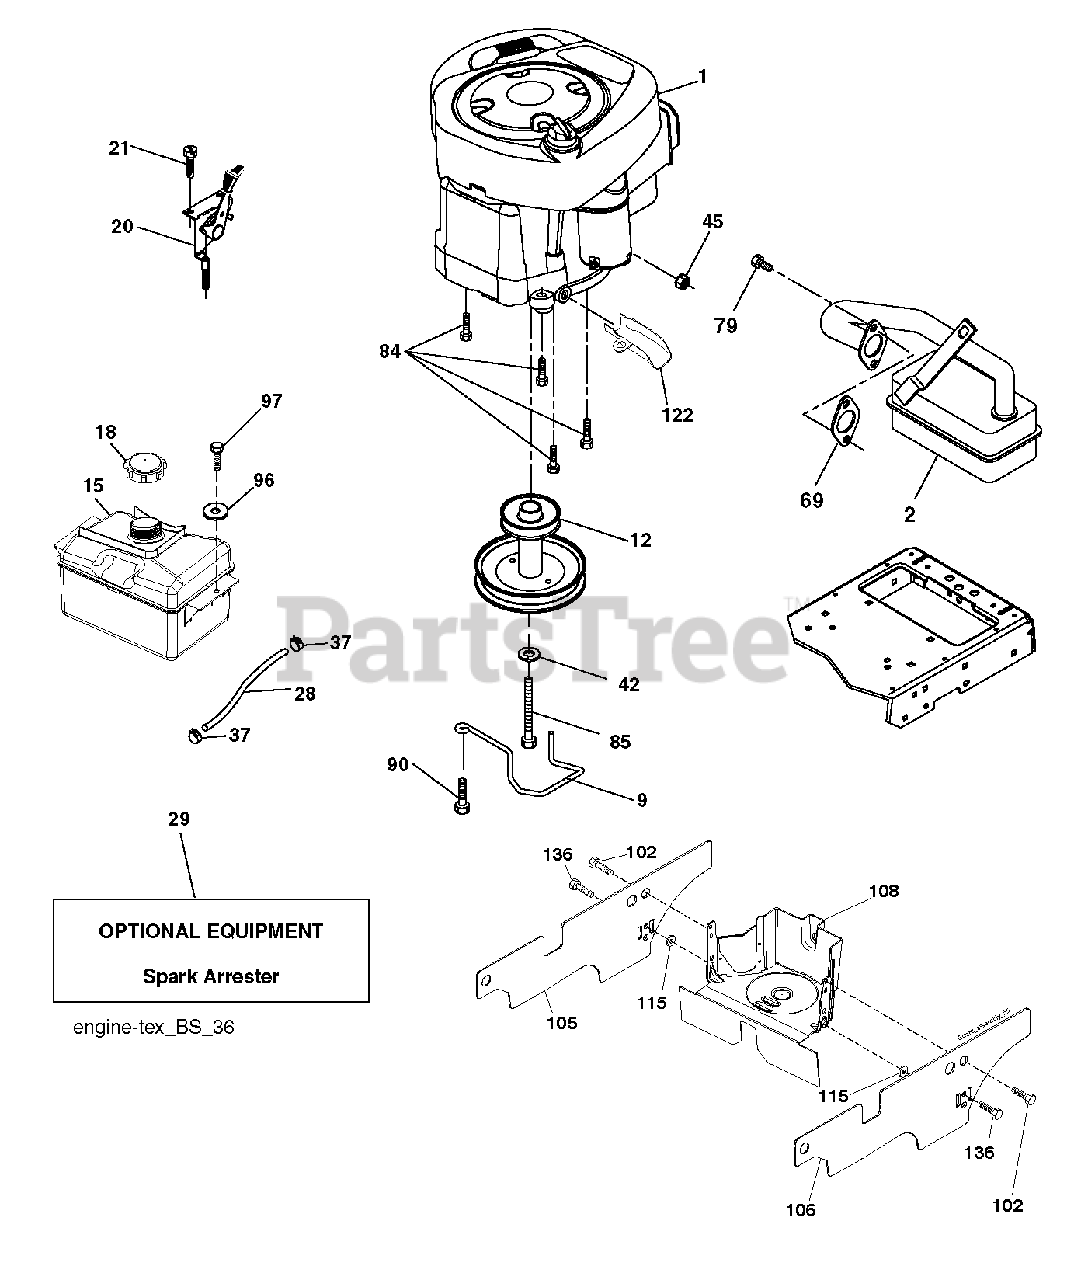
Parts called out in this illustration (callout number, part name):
2	MUFFLER.SINGLE.CYL.KOHL/B&S
9	KEEPER BELT ENGINE
12	PULLY ENGINE
15	RP TANK FUEL FRT 1.5 GAL
18	CAP ASM.FUEL.2.25"FR.
20	CONTROL.TH/CK.C.
21	SCREW.#10 X 0.750.BOS
28	LINE.FUEL.20
29	KIT.SPARK ARRESTOR 794945 B&S
37	HOSE CLAMP
42	LOCKWASHER
45	NUT
69	GASKET.EXHAUST.KOHLER
79	SCREW.SOCKET HD.5/16-1
84	SCREW.3/8-16
85	BOLT HEX 7/16-20X4-1/4"
90	SCREW 3/8-16X1
97	SCREW HEXWSHR 1/4-20X3/4
102	SCREW
105	SHIELD.SIDE.LH.3842"TEX FRENCH
106	SHIELD.SIDE.RH.3842"TEX FRENCH
108	ENGINE COVER
115	PALNUT 1/4
122	EXTENSION DRAIN OIL
136	SCREW.1/4-20X5/8
